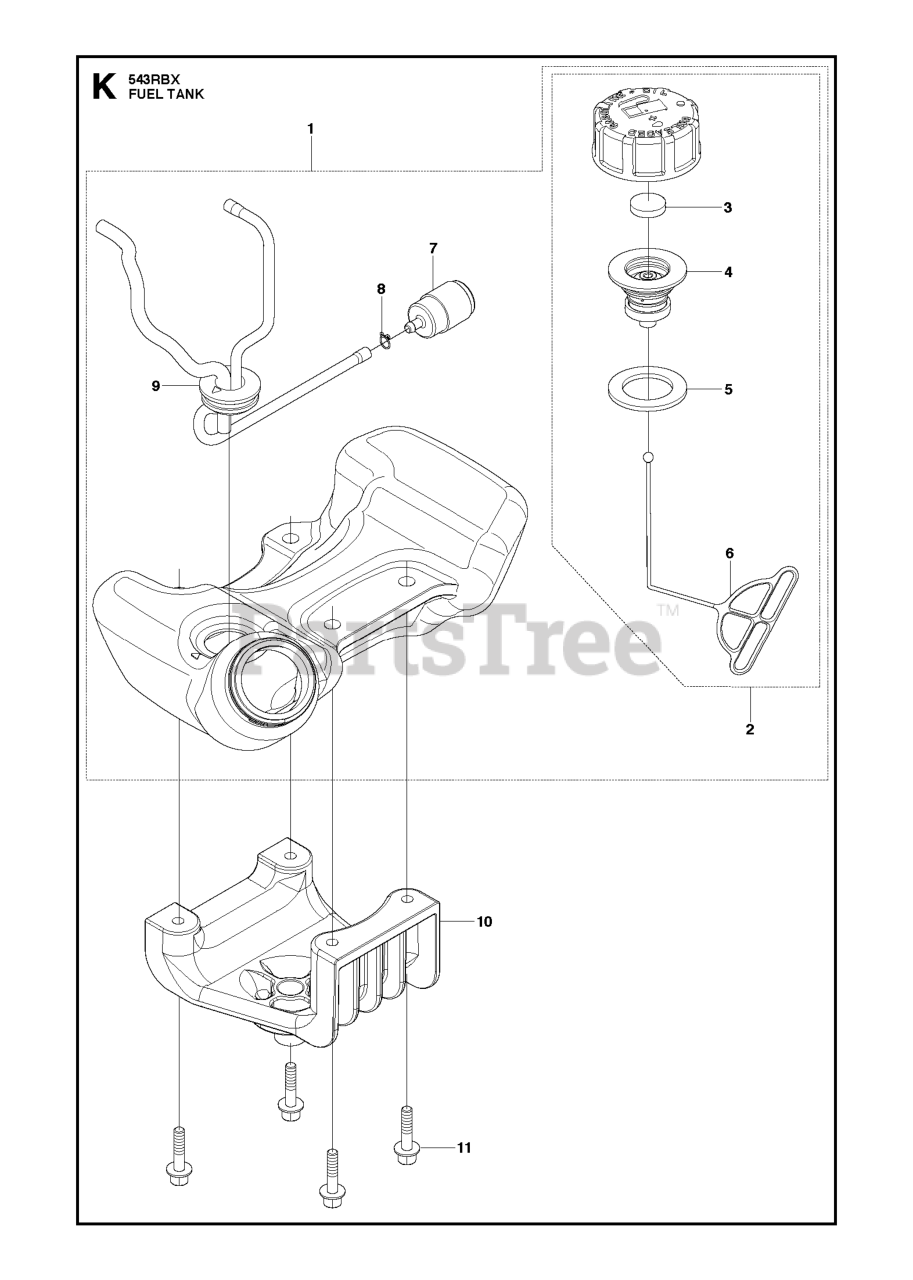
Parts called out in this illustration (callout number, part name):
2	ASSY FUEL CAP
7	FILTER
11	BOLT M5X25
